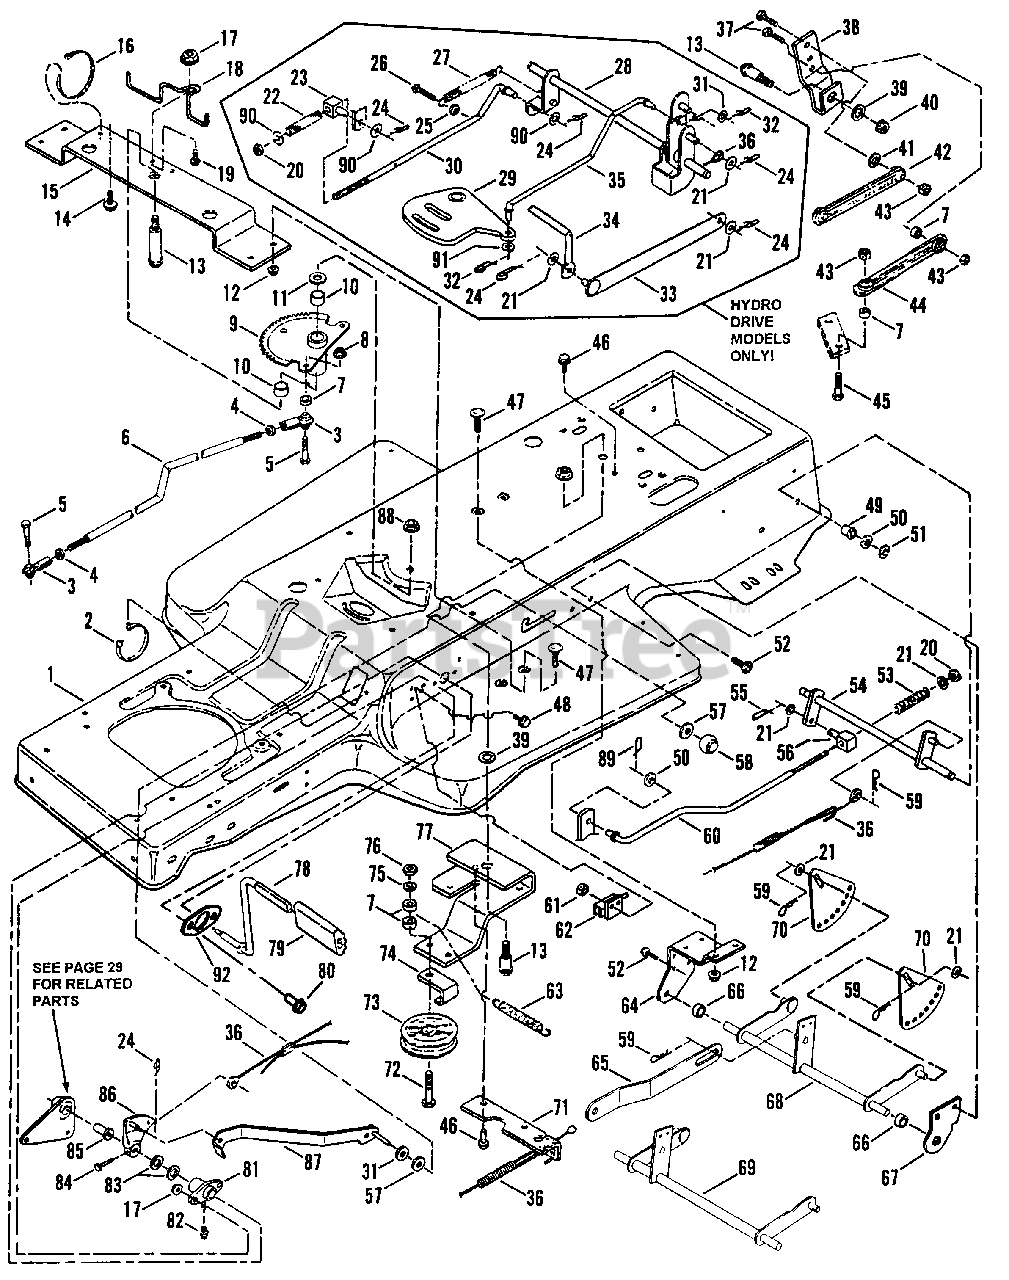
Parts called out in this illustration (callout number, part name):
1	FRAME, Tractor
2	TIE, Wire
3	BALL JOINT, 3/8-24
4	NUT, 3/8-24 Hex Jam
5	SCREW, 3/8-24 x 1-1/4" Hex Head Cap
6	LINK, Drag
7	SPACER
8	NUT, 3/8-16 Hex Flange Lock
9	ASSEMBLY, Sector Gear
10	BEARING, Sector Gear
11	WASHER, 3/4 Thrust
12	NUT, 1/4-20 Hex Flange Lock
13	BOLT, 1/2-13 x 2" Hex Flng. Lk.
14	SCREW, #10-24 x 1/2" Hex Washer Self-Tap (Torx)
15	BRACE, Sector Gear
16	TIE, Cable
17	NUT, 5/16-18 Hex Flange Lock
18	GUIDE, Drive Belt
19	BOLT, 5/16-18 x 3/4" Hex Flng. Lk.
20	NUT, 3/8-16 Hex Nyloc
21	WASHER, 3/8" Flat
22	SPRING, Brake
23	SWIVEL, Inline Brake
24	PIN, 3/64 x 1-7/32" Cotter (Self-Lkg.)
25	NUT, 5/16-18 Hex Center Lock
26	SCREW, 5/16-18 x 1-1/4" Self-Tapp.
27	SPRING
28	WELDMENT, Brake Arm
29	ARM, Transmission Speed Control
30	ROD, Brake
31	WASHER, 5/16 Flat
32	PIN, 5/16 Cotter, Self-locking
33	LINK, Shift
34	ASSEMBLY, Shift Lever (Lower)
35	LINK, Speed
36	ASSEMBLY, Clutch/Brake Cable
37	SCREW, 3/8-16 x 1 1/4" H. H. C.
38	BELLCRANK, Shift Lever
39	WASHER, 1/2 Internal Tooth Lk.
40	NUT, 1/2-13 Hex Flange Lock
41	WASHER, 3/8 Split Lock
42	LINK, Shift Lever
43	NUT, 3/8-16 Hex Center Lock
44	LINK, Shift Lever (Twisted)
45	SCREW, 3/8-16 x 1 1/2" H. H. C.
46	SCREW, 5/16-18 x 5/8" Self-Tap
47	BOLT, 1/4-20 x 5/8" Carriage
48	SCREW, #10-32 x 5/8" H. W. H.
49	BEARING, Nylon
50	WASHER, 1/2 Flat
51	RING, 1/2" External Retaining
52	SCREW, 5/16-18 x 5/8" Truss Head (Torx)
53	SPRING, Brake
54	WELDMENT, Brake Pivot
55	COTTER-PIN, 1/16" x 1.42" Self-Locking
56	SWIVEL, Brake Link
57	WASHER, 5/16 Nylon
58	KNOB, Push/Pull
59	PIN, 3/32 x 1-1/2" Hair
60	ROD, Brake
61	NUT, #10-32 Hex Nyloc
62	SWITCH
63	SPRING
64	BRACKET, Rear Lift/PTO Lever
65	LINK, Lift
67	BRACKET, Deck Hang Pivot
68	WELDMENT, Rear Lift
69	WELDMENT, Rear Lift
70	PLATE, Lift Sector
71	EXTENSION, Idler Arm
72	SCREW, 3/8-16 x 2-1/4" Hex Head Cap
73	PULLEY
74	GUIDE, Pulley
75	WASHER, 3/8 Split Lock
76	NUT, 3/8-16 Hex
77	ARM, Idler (Traction Drive)
78	PEDAL, Park Brake
79	PAD, Pedal
80	SCREW, 3/8-16 x 7/8" Truss Head (Torx)
81	ASSEMBLY, Foot Shaft Pivot
82	FITTING, Lube
83	WASHER, 5/8 Flat
84	PIN, 3/16 x 1 1/2" Clevis
85	BEARING, Flange
86	ASSEMBLY, Clutch Brake Arm
87	LATCH, Park Brake
88	NUT, 1/2-13 Hex Center Lock
89	PIN, 1/16 x 1 27/64 Cotter (Self-Locking)
90	WASHER, 3/8" Flat
91	WASHER, 11/32" Flat Grade 5
92	WASHER, Pivot-Stiffener
